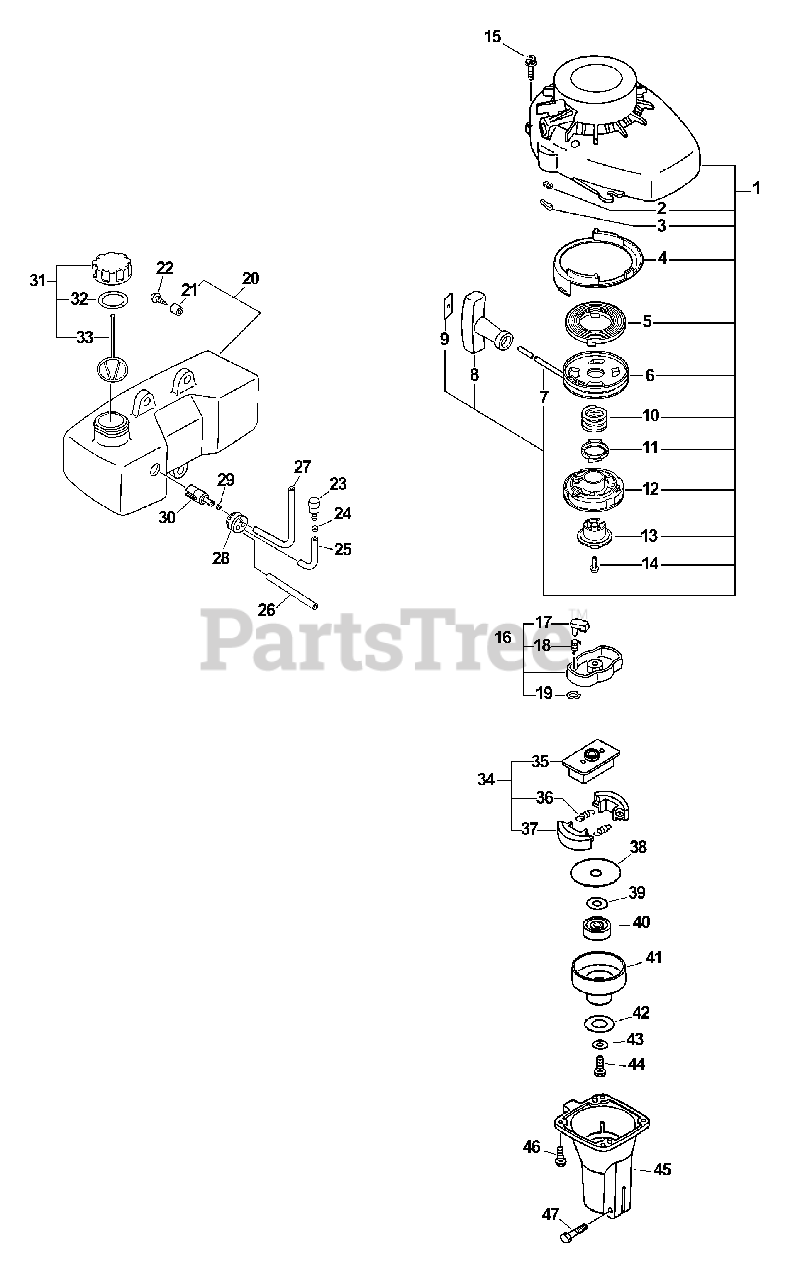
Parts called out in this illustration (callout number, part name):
1	STARTER ASSY
3	PAWL, STARTER
4	CASE, STARTER
5	SPRING, RECOIL
6	PULLEY, STARTER
7	ROPE, STARTER
8	GRIP, STARTER
9	RETAINER, ROPE
10	SPRING, RETURN
11	PAWL, STARTER
12	SPRING ASSY
13	PLATE, CAM
15	SCREW 4×16
16	PAWL ASSY, STARTER
17	PAWL, STARTER
18	SPRING, RETURN
19	E-RING 4
20	TANK ASSY, FUEL
21	SPACER 6.2×7.8×6
22	SCREW 5×15
23	VENT ASSY
25	PIPE, FUEL 3x-5x-70 BLACK
26	PIPE, FUEL 3×6×50
27	PIPE, FUEL 3×5×210 BLACK
28	GROMMET, FUEL
29	CLIP 6 MM
30	FILTER, FUEL
31	CAP ASSY
32	GASKET, FUEL CAP
33	CONNECTOR, CAP L= 100 MM
34	CLUTCH ASSY
35	HUB, CLUTCH
36	SPRING, CLUTCH
37	SHOE, CLUTCH
38	PLATE, CLUTCH
39	WASHER 10.5×18×1.6
40	BEARING, BALL 6000-2RLB
41	DRUM, CLUTCH
43	WASHER, CLUTCH
44	SCREW 6×12
45	CASE, CLUTCH
46	SCREW 4×14
47	BOLT 5
